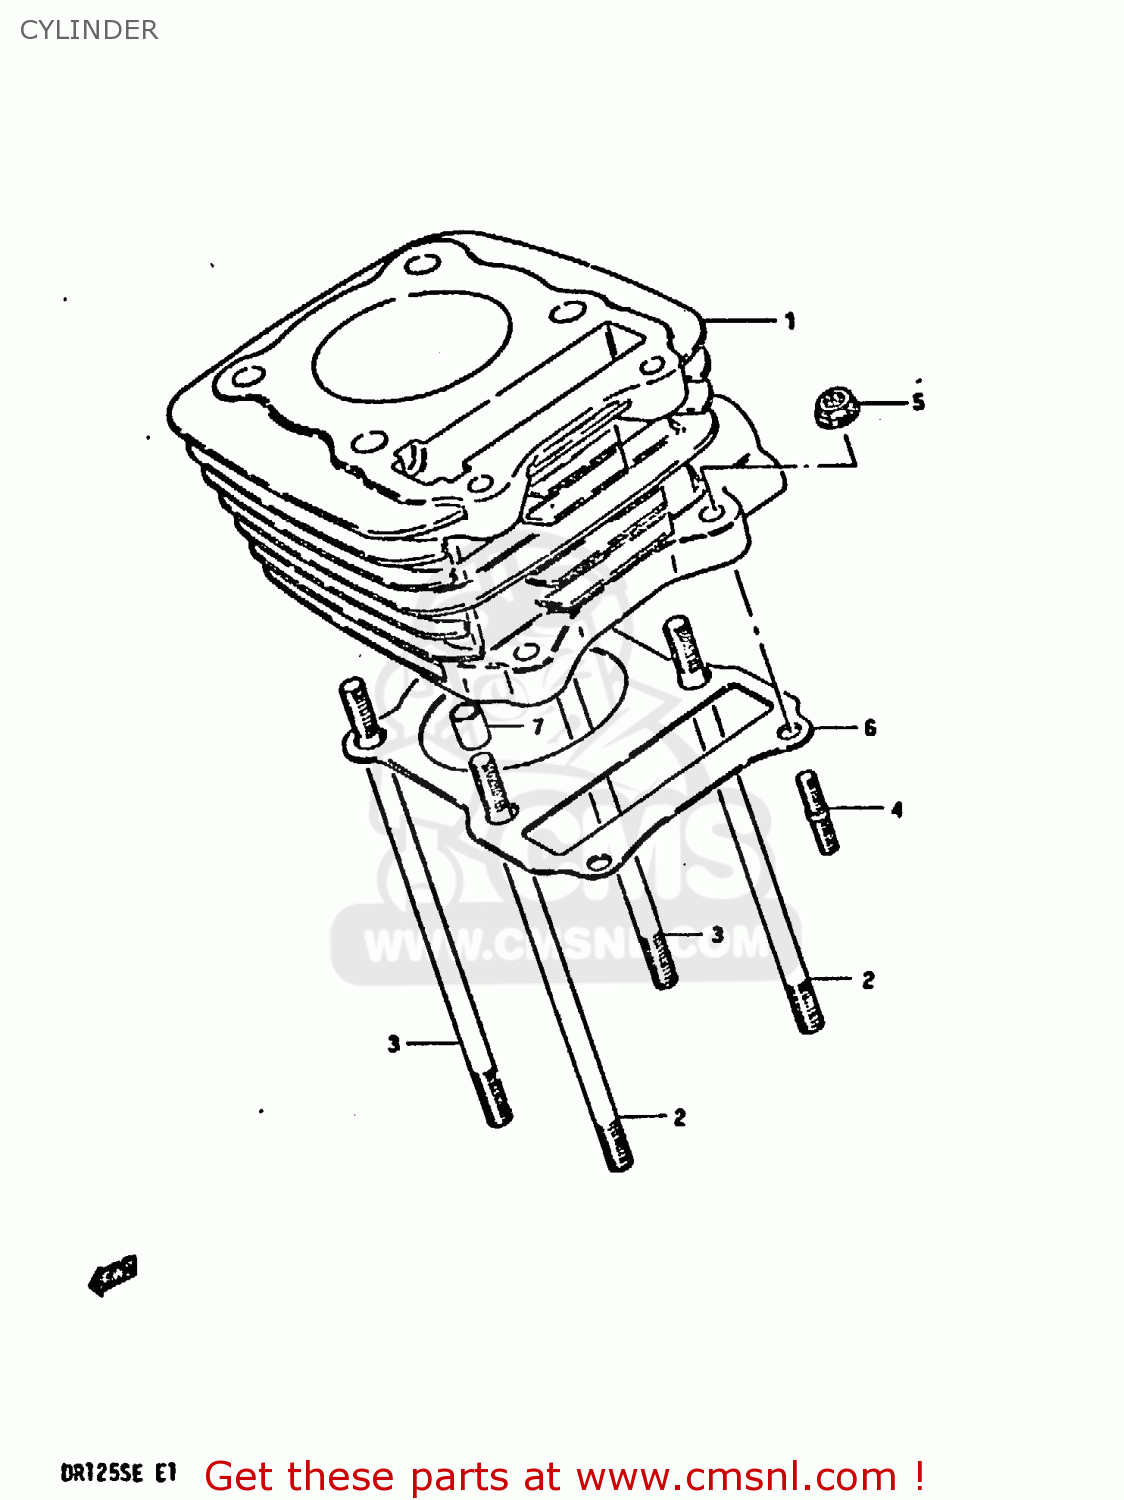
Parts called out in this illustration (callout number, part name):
1	CYLINDER
2	BOLT,STUD
3	BOLT,STUD
4	STUD 6X25
5	NUT
6	GASKET,CYLINDER (MCA)
7	PIN
